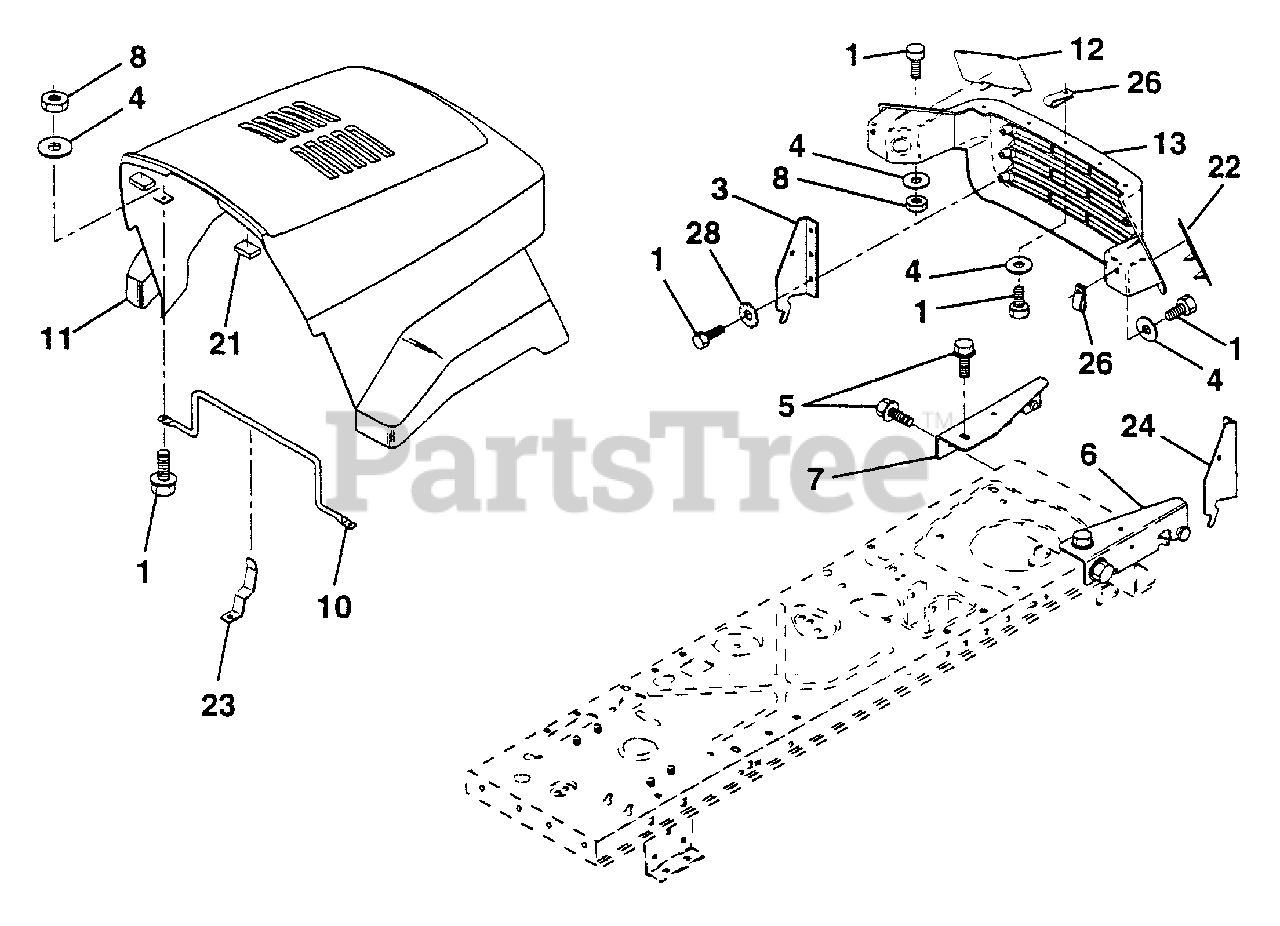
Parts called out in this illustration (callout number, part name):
1	Bolt Fin Hex 1/4-20 x 5/8
3	Bracket Pivot Hood LH
4	Washer 9/32 x 3/4 x 16 Ga.
5	Screw Thdrol 5/16-18 x 3/4
6	Bracket Asm. Pivot Hood RH
7	Bracket Asm. Pivot Hood LH
8	Nut Keps 1/4-20
10	Brace Hood
13	Grille
21	Bumper Hood
23	Latch Hood
24	Bracket Pivot Hood RH
26	Clip Tinnerman
28	Washer Lock Ext Tooth
